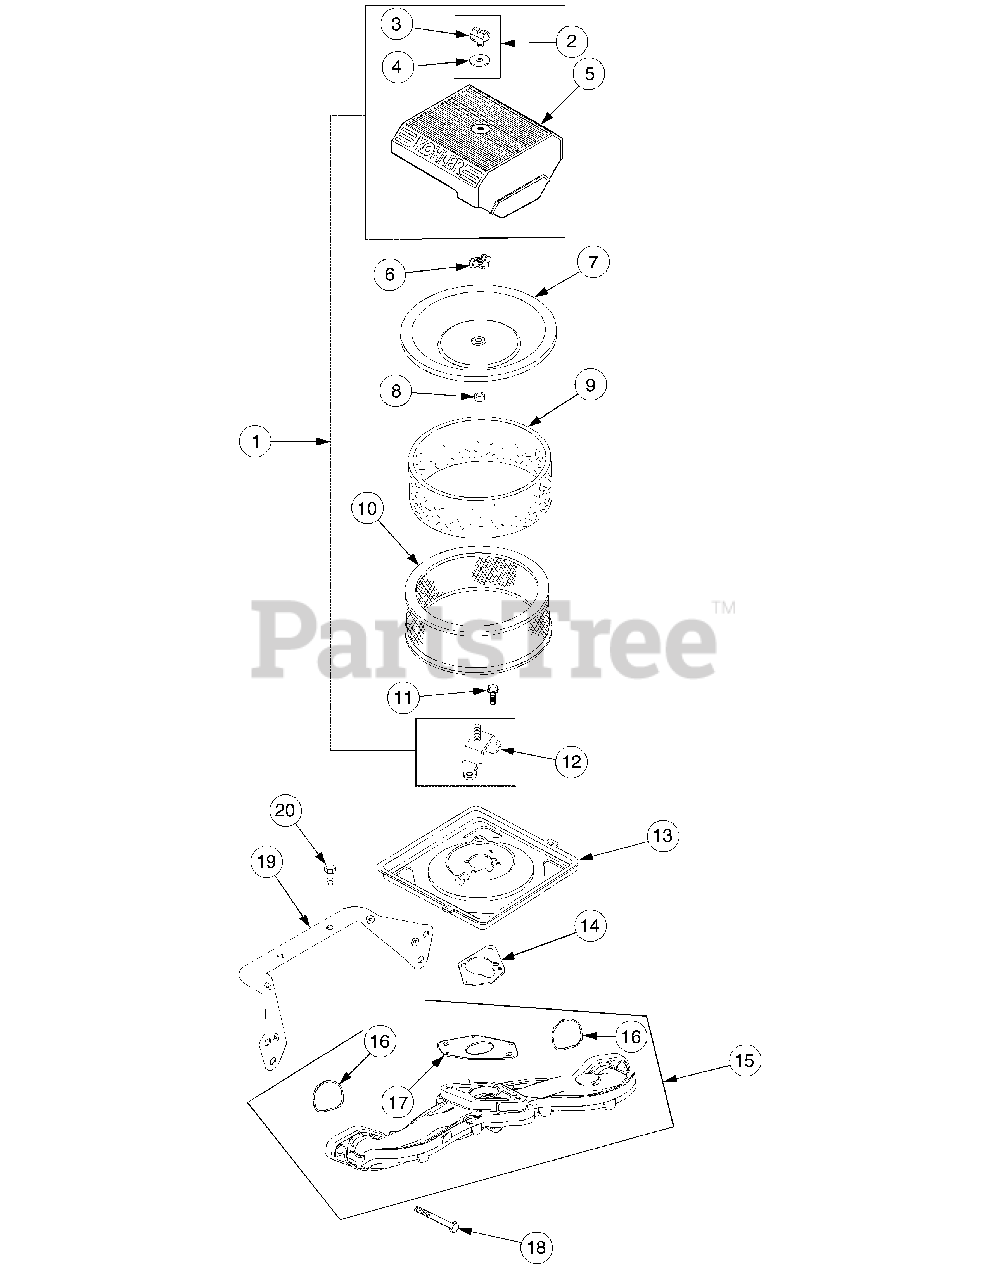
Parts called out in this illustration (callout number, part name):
1	Kit, Air Cleaner Cover
2	Kit, Knob w/Seal
4	Seal, Air Cleaner Cover Knob
5	Cover, Air Cleaner
7	Cover, Inner Air Cleaner
8	Seal, Inner Air Cleaner
9	Precleaner, Element
10	Element, Air Cleaner
11	Screw, Hex Flange, M6 x 1.0 x16
12	Bracket, Air Cleaner Base
13	Base, Air Cleaner
14	Gasket, Air Cleaner Base
15	Manifold, Intake
16	O-Ring, Intake Manifold
17	Gasket, Carburetor
18	Screw, Hex Flange, M6 x 1.0 x 40
19	Bracket, Air Cleaner Base
20	Screw, Hex Flng, M5 x 0.8 x 10
